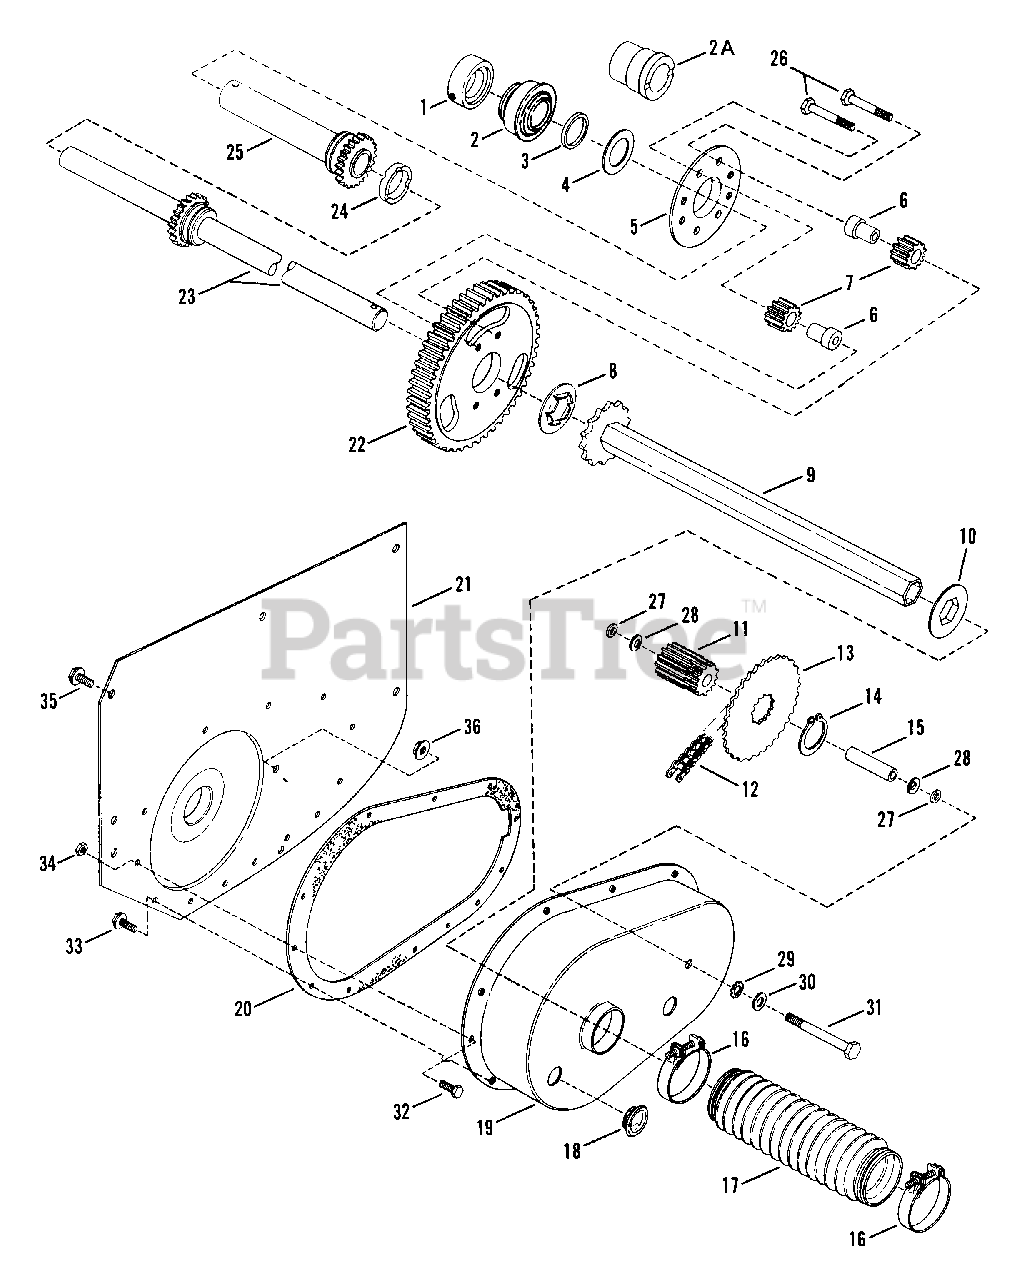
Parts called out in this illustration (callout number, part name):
1	COLLAR, Lock
2	BEARING, Axle (Right Hand Fender)
2A	BEARING, Axle (Right Hand Fender)
3	SPACER, Short Axle
4	WASHER, Thrust
5	PLATE, Differential
6	SPACER, Pinion
7	GEARS, Differential Pinion
8	WASHER, Thrust
9	ASSEMBLY, Drive Hex Tube
10	WASHER, Hex Insert
11	GEAR, 11 Teeth-10 Pitch
12	CHAIN, 46 Pitch (#35)
13	SPROCKET
14	RING, Retaining
15	SPACER
16	CLAMP, Boot
17	BOOT, Oil Seal
18	PLUG, Oil Fill & Check
19	CASE, Transmission
20	GASKET, Transmission Case
21	FENDER, Right Hand (2.498" ID Hole)
22	GEAR, 63 Teeth-10 Pitch
23	AXLE, Long
24	SPACER, Differential (1.25" ID x .425 Wide)
25	AXLE, Short
26	SCREW, 5/16-24 x 1-5/8" Hex Cap Special Lock
27	O-RING, 5/16"
28	WASHER, Belleville
29	WASHER, 5/16 External Tooth Lock
30	WASHER, 5/16 Flat
31	BOLT, 5/16-24 x 2-5/8" Idler
32	SCREW, 1/4-20 x 5/8" Hex Head Cap
33	SCREW, 1/4-20 x 5/8" Self-Tapping
34	NUT, 1/4-20 Hex Center Lock
35	SCREW, 5/16-18 x 5/8" Self-Tapping
36	NUT, 5/16-24 Hex Flange Lock
